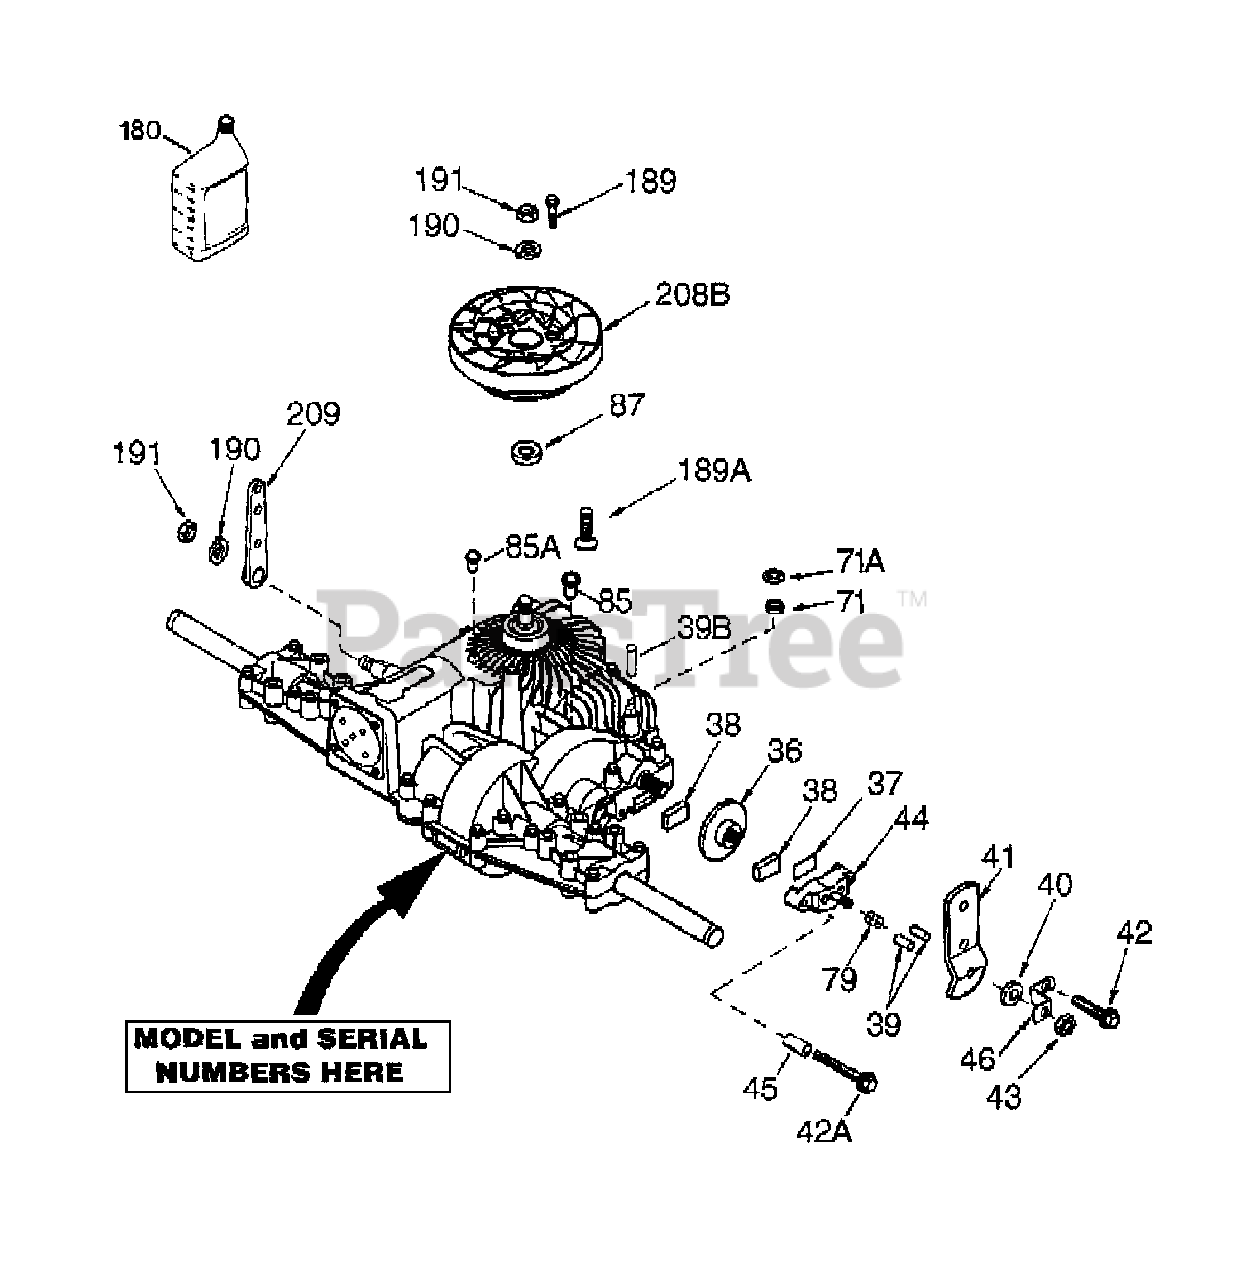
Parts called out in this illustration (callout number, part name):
36	Brake Disc
37	Brake Pad Plate
38	Brake Pad
39	Dowel Pin
39B	Belt Guard
40	Flat Washer
41B	Brake Lever
42	Screw, 1/4-20 x 1-1/4"
42A	Screw, 1/4-20 x 2-1/4"
43	Locknut, 5/16-24
44	Brake Pad Holder
46	Brake Lever Bracket
71	Square Cut Ring
71A	Pushnut, 9/16"
85	Oil Fill Plug
85A	Tube, Plug
87	Oil Seal, 5/8"
180	Gear Oil 80W90
189	Drive Screw #6 x 1/2"
189A	Screw, 10-32 x 1/2"
190	Lockwasher
191	Nut, 7/16-20
208B	Fan/Coupling
209	Control Lever
